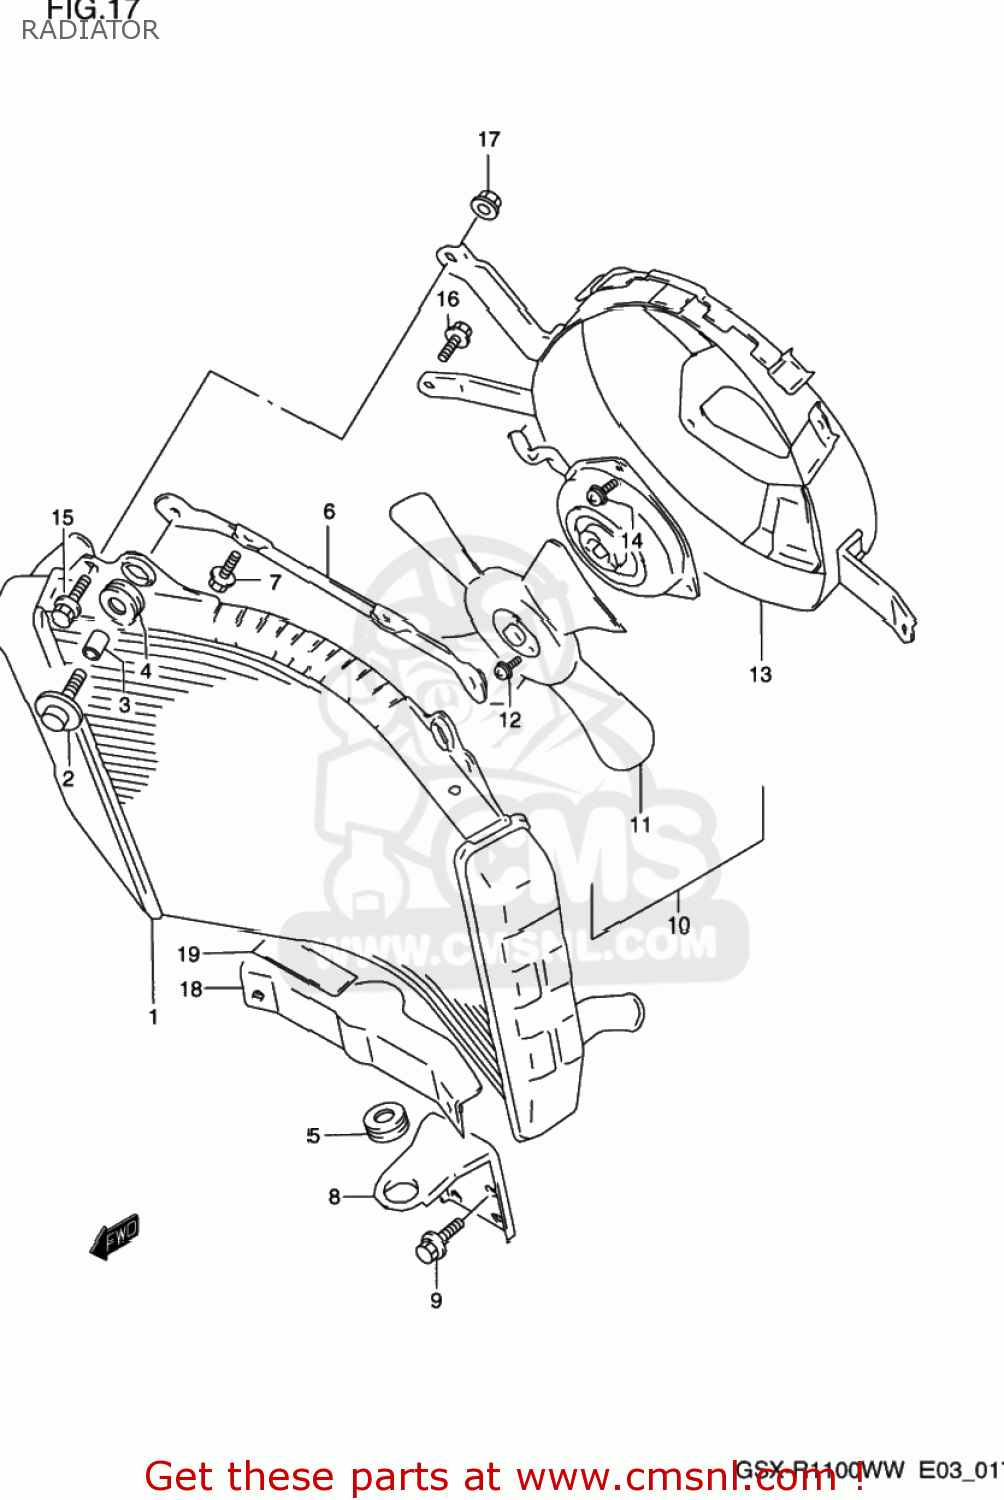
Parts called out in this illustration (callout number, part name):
1	RADIATOR ASSY,WATER
2	BOLT(6X25)
3	SPACER(6.5X10.5X12)
4	CUSHION,RADIATOR LWR
5	CUSHION
6	BRACKET COMP,RADIATOR
7	BOLT
8	BRACKET,RADIATOR,LOWER
9	BOLT
10	FAN ASSEMBLY,RADIATOR
11	FAN
12	BOLT
13	SHROUD
14	BOLT
15	BOLT
16	BOLT
17	NUT
18	BRACKET,RADIATOR,LOWER,NO
19	CUSHION(50X42X2.0)
